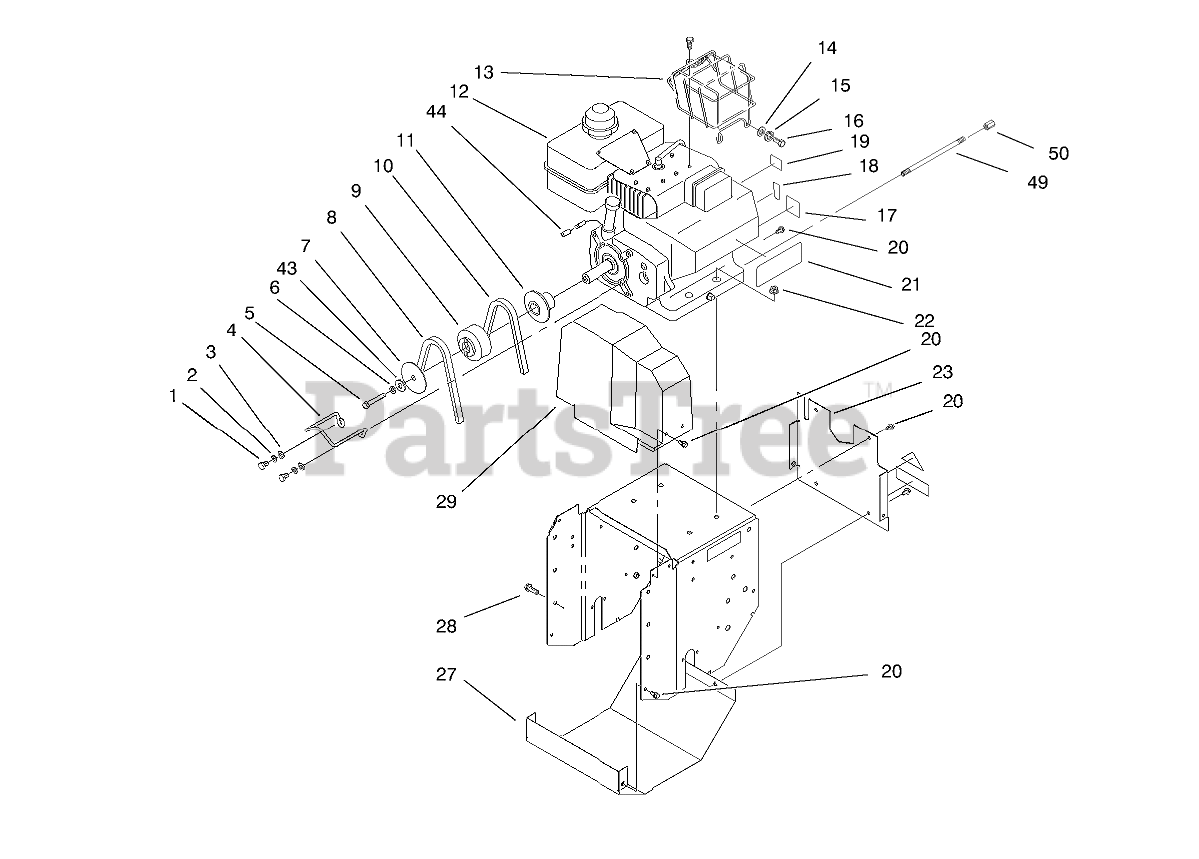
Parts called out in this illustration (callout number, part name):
1	SCREW-HH
2	WASHER-LOCK
3	WASHER-PLAIN
4	GUIDE-BELT
5	SCREW-HH
6	WASHER-LOCK
7	SHEAVE-HALF, IMPELLER
8	V-BELT, IMPELLER
9	PULLEY-ENGINE CENTER
10	V BELT-TRACTION
11	SHEAVE-HALF, TRACTION
13	Guard-Muffler (Only On: 38084)
14	Washer-Flat (Only On: 38084)
15	Washer-Lock (Only On: 38084)
16	Screw-Self Drilling (Only On: 38084)
17	DECAL - PRIMER
18	DECAL-THROTTLE
19	DECAL-CHOKE
20	SCREW-HWH
21	Decal-Hot Surface (Only On: 38083)
21	Decal-Hot Surface (Only On: 38084)
22	NUT-HF
23	Plate-Back
27	Cover-Lower Traction
28	SCREW-HWHTF
29	COVER-UPPER BELT
43	WASHER
44	CAP-WIRE, LITE
49	NIPPLE-PIPE
50	CAP-PIPE
